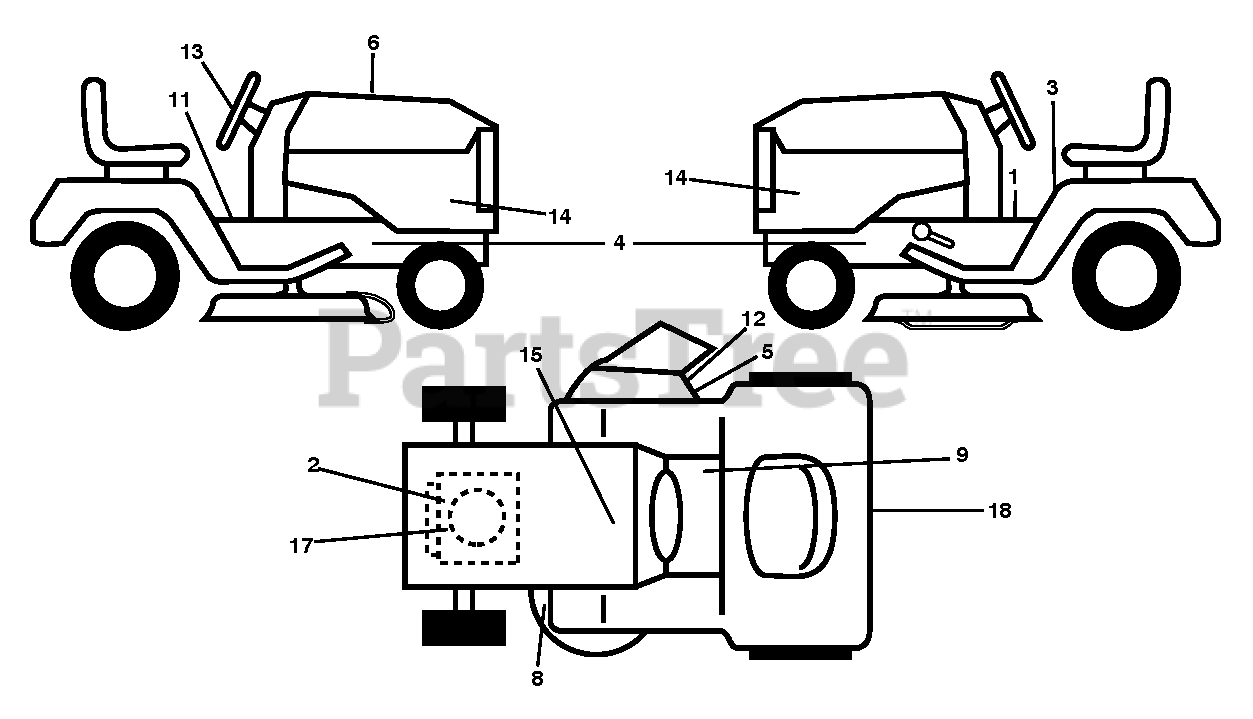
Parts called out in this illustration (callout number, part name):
1	DECAL PARK BRAKE
5	DECAL, DEFLECT WARNING
8	DECAL.MOWER.SCH.48/54
12	DECAL.INTERNATIONL.CUTFINGER
15	DECAL BTRY SYMBOLS
